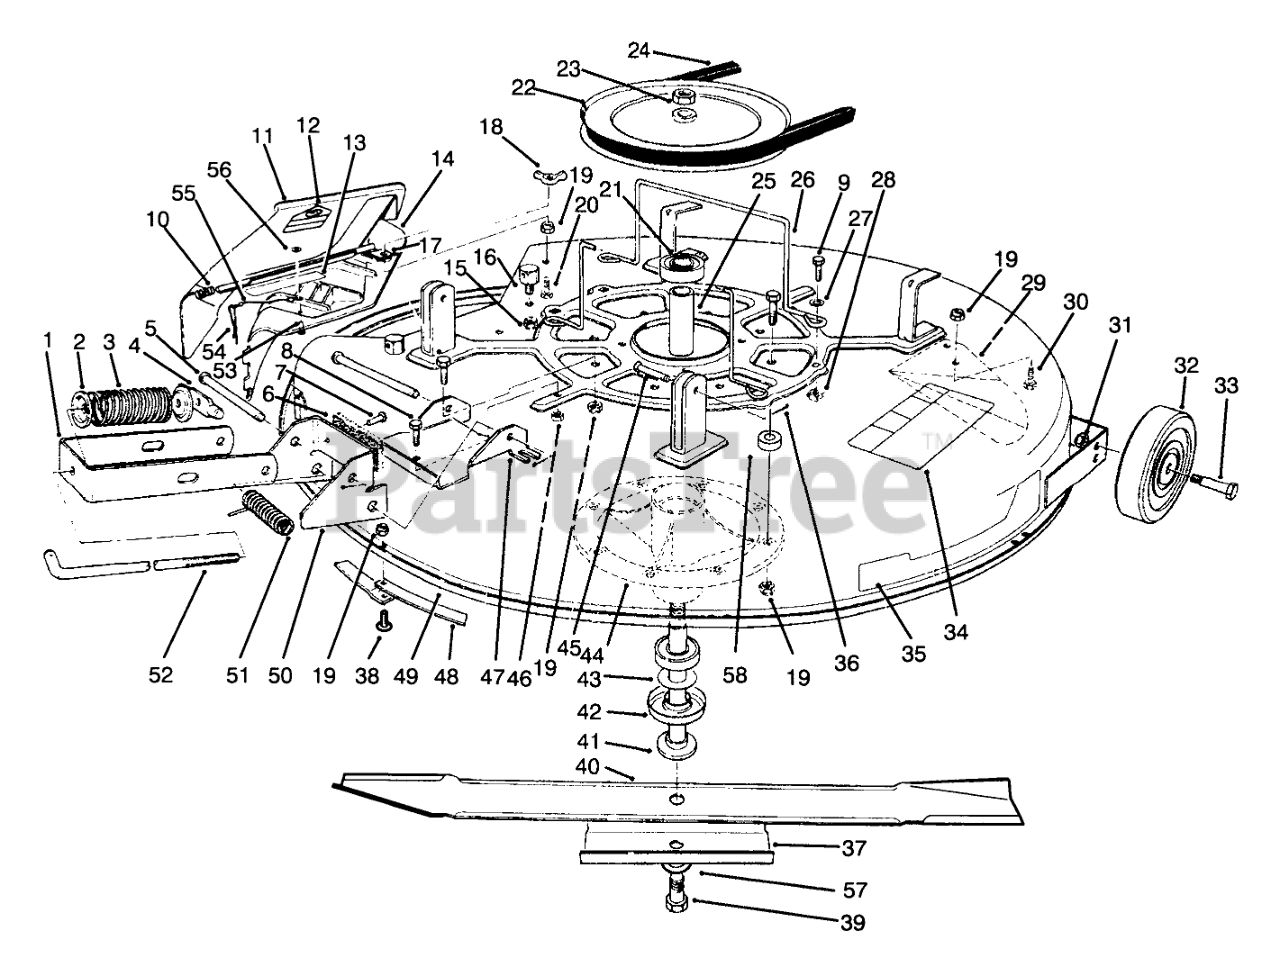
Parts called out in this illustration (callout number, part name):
1	Bracket-Engagement
2	RETAINER-SPR. TOP
3	SPRING-COMPRESSION
4	SHAFT-DECK ADJ.
5	PIN-CLEVIS
6	PAD-BRAKE
7	RIVET-BLIND
8	SCREW-HH
9	SCREW-HH
10	SPRING
11	Assembly-Deflector (Incl. Ref. #12)
12	DECAL-DANGER
13	DECAL-DANGER, DEFLECTOR
14	Assy.-Cover, Discharge (Incl. Ref. #53-56)
15	NUT-LOCK, NI
16	POST-PIVOT
17	Brace-Cover, Rear
18	NUT-WING
19	NUT-LOCK, NI
20	SCREW-HH
21	BEARING-BALL
22	PULLEY
23	NUT-HEX
24	V-BELT, DECK
25	SPACER-BEARING
26	GUIDE-BELT
27	WASHER-PLAIN
28	NUT-RETAINER
29	Kicker
30	SCREW-HH
31	NUT-LOCK, NI
32	WHEEL-DECK
33	BOLT-WHEEL
34	DECAL-DANGER, THROWN OBJECT
35	DECAL-RECYCLER
36	PIN-COTTER
37	STIFFENER
38	SCREW-PPH
39	SCREW-HH
40	Blade
41	SHAFT-SPINDLE
42	SHIELD-BEARING
43	SPACER-HARDNED
44	SPINDLE
45	PIN-CLEVIS
46	NUT-HEX
47	Plate-Deck, Brake Mtg.
48	RING-DECK
49	Deck-Cutting, Recycler (Incl. Ref. #13 & 34)
50	Assembly-Brake (Incl. Ref. #6-7)
51	SPRING
52	ROD-ENGAGEMENT
53	RIVET-BLIND
54	PIN-LOCKING, CHUTE
55	LANYARD
56	WASHER-PLAIN
57	WASHER-BELLEVILLE
58	SPACER-PIN, MOUNTING
